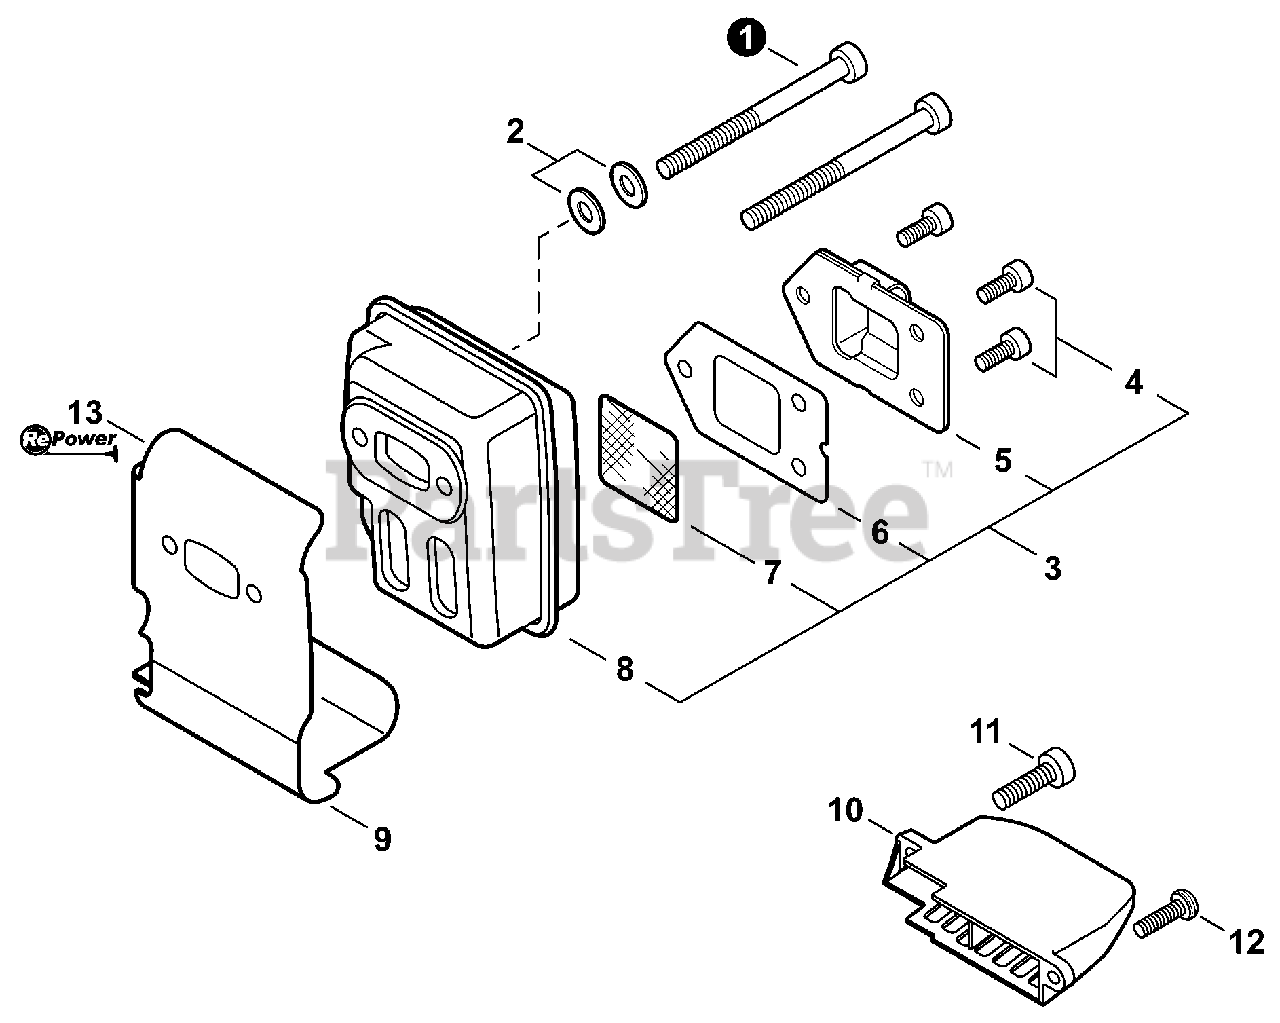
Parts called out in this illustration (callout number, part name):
1	BOLT, TORX 5x55
2	WASHER, FLAT 5.5x10x0.8
3	MUFFLER ASSY
4	BOLT, TORX 4x8
5	GUIDE, EXHAUST
6	GASKET, EXHAUST
7	SCREEN, SPARK ARRESTER
9	HEAT SHIELD, EXHAUST
10	COVER, MUFFLER
11	BOLT, TORX 5x16
12	BOLT, TORX 5x16
13	GASKET KIT: ENGINE, INTAKE, EXHAUST
